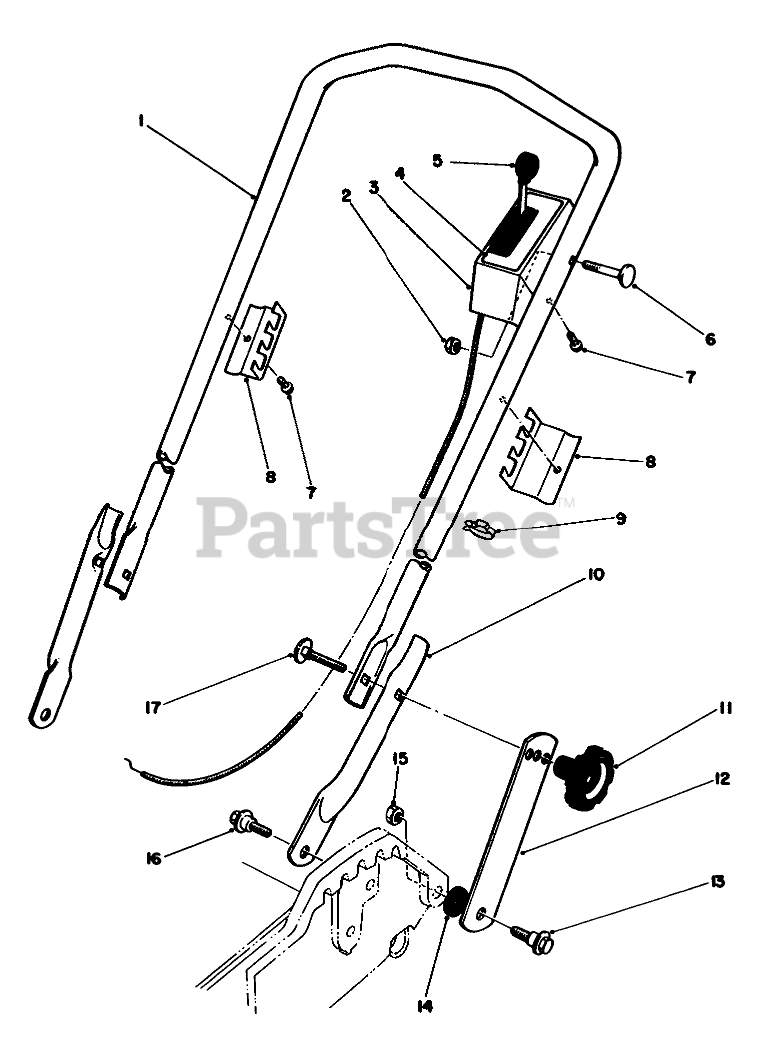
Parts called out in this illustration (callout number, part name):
1	UPPER HANDLE/DECAL
2	NUT-LOCK, NI
3	Cover-Control (Incl. Ref. #4)
4	Decal-Control Cover
5	THROTTLE CONT-SERVICE
6	HANDLE SCREW
7	SCREW-HWHTF
8	Bag Support
10	Hand-Lower
12	Handle Latch
13	SCREW-SHOULDER
14	SPACER
15	NUT-LOCK, NI
16	SCREW-SHOULDER
17	5/16-18 X 2 HNDLE SCREW
